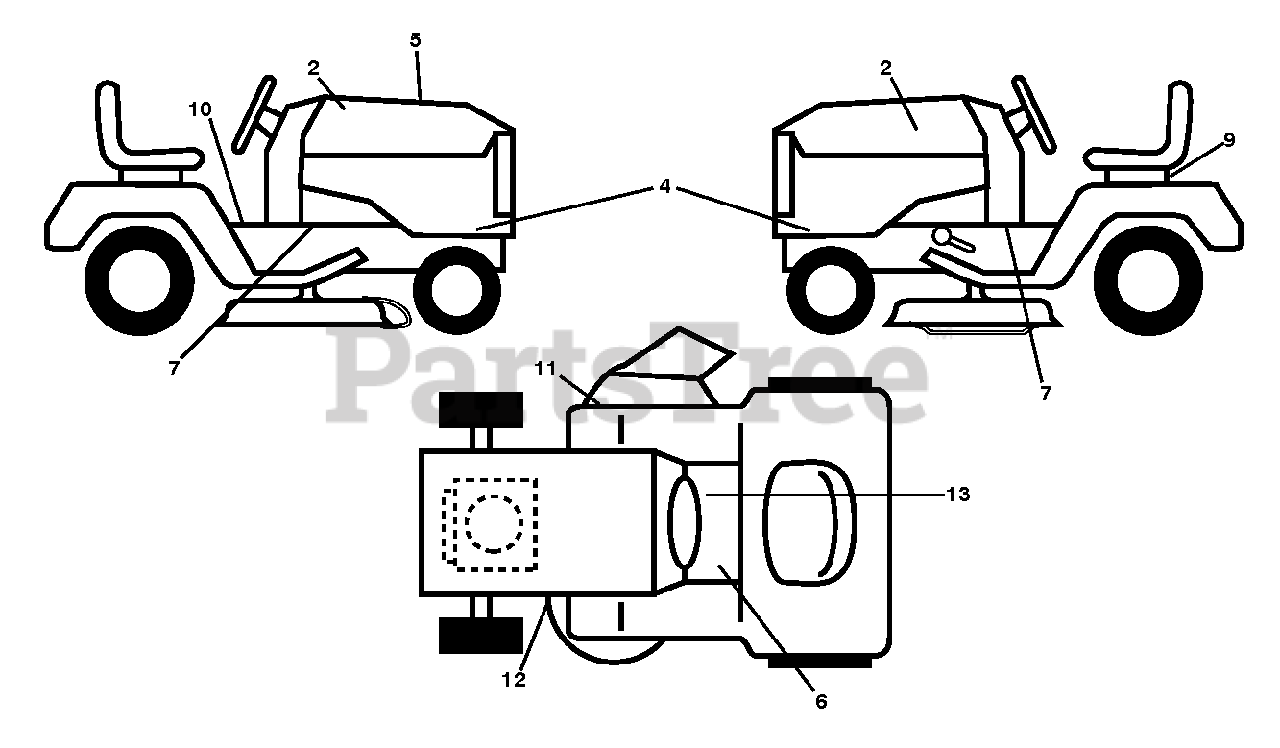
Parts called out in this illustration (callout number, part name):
2	DECAL.BADGE.170MM.TEXTLOGO.
6	DECAL.FNDR.SDLE.BRAKE.CLUTCH.6
7	DECAL.CHASSIS.HOT.MUFFLER
9	DECAL BTRY SYMBOLS
10	DECAL.READ.OWN.MAN.SYMBOL.LT
11	DECAL.WARN.DFLCTR/CTFNGR.SRD.
12	DECAL.V.BELT.30"
13	DECAL.PARKING.BRAKE.SADDLE.LT
